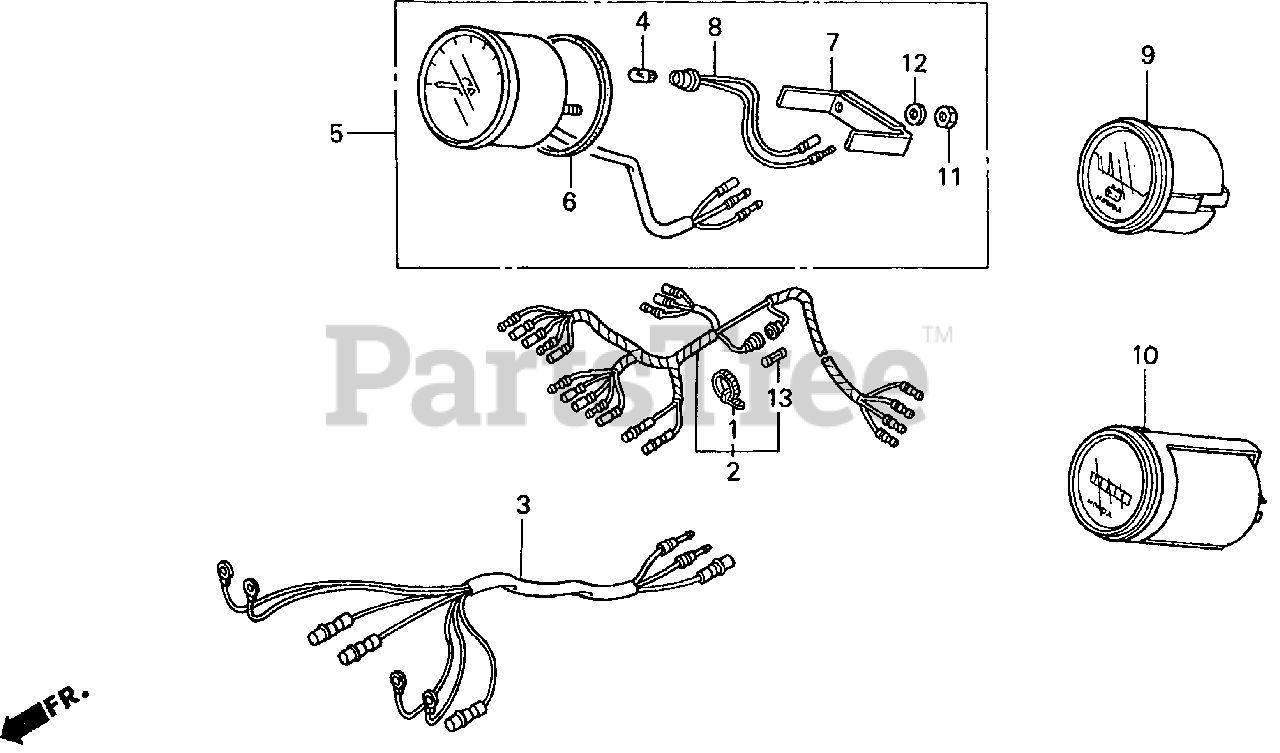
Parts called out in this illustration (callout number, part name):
1	BAND B1, CABLE
2	HARNESS ASSY., METER (A)
3	HARNESS ASSY., METER (B)
4	BULB, WEDGE BASE (12V1.7W) (NIPPON SEIKI)
5	TACHOMETER ASSY. Use up to Frame SN 3000661.
5	TACHOMETER ASSY. Use from Frame SN 3000662.
9	METER ASSY., VOLT
10	METER ASSY., HOUR L.C.D.
11	NUT, HEX. (5MM)
12	WASHER, SPRING (5MM)
13	FUSE A (10A)
